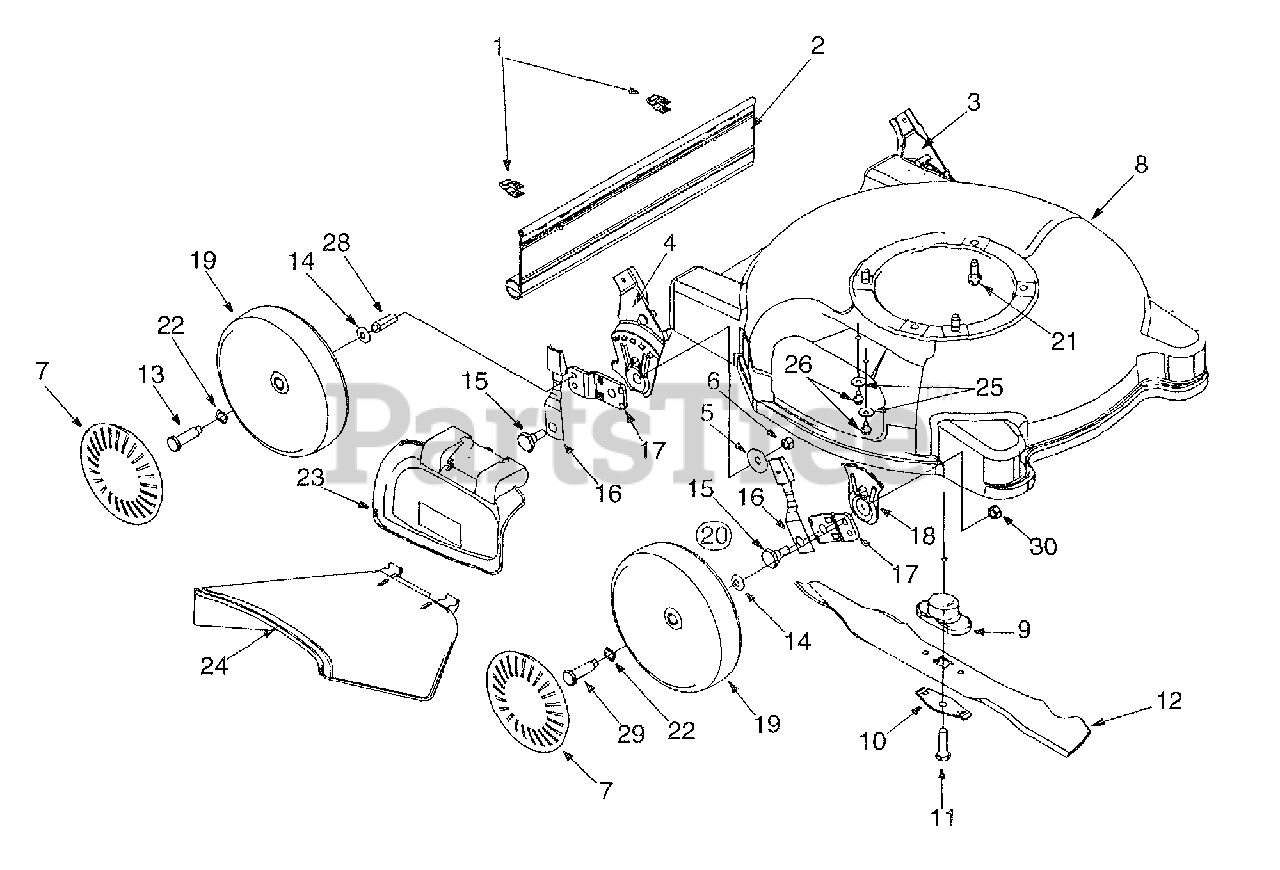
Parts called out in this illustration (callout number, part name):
1	Hinge Clip
2	Rear Flap
3	Handle Bracket Ass'y LH
4	Handle Bracket Ass'y RH
5	Bell Washer .39" ID x 1.38"
6	Hex Nut 3/8-16 Thd.
7	Hub Cap:Beige
10	Blade Bell Support
11	Hex Bolt 7/16-20 x 1.5"
12	18" Mulch Blade
13	Axle Bolt
14	Bell Washer .400" ID x .88"
15	Shoulder Bolt
16	Spring Lever Ass'y w/Knob
18	Height Adj. Plate
19	Wheel Assembly
20	Height Adj. Ass'y. Comp. R.F.
21	Hex Lock Wash. Hd. Screw 3/8-16 x 1.0" Lg.
22	Wave Washer
23	Mulching Plug
24	Chute Deflector
25	Bell Washer
26	Hex Wash. Hd. TT Screw 1/4 20 x .5" Lg.
28	Spacer
29	Axle Bolt
30	Hex Flange L-Nut 3/8-16 Thd.
